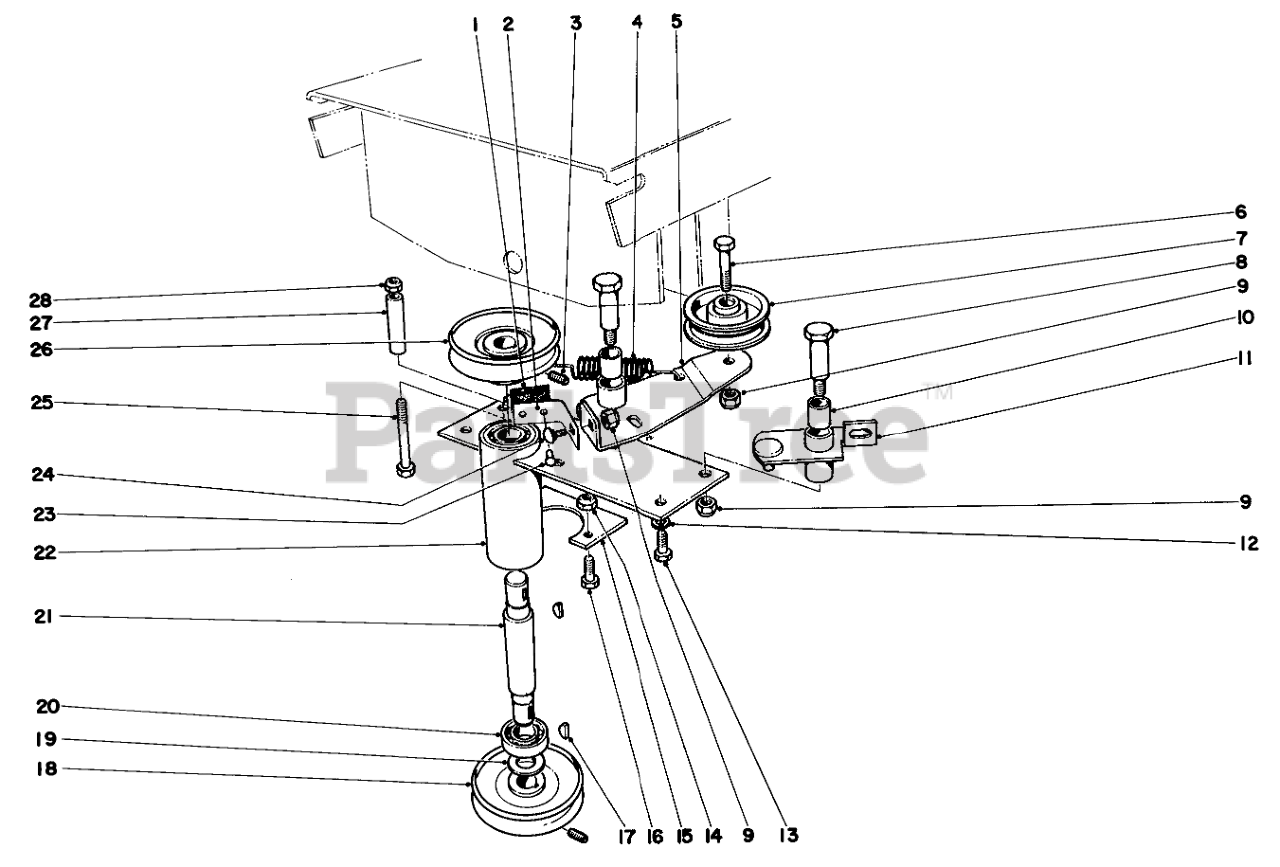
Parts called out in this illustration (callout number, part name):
1	BLADE BRAKE LINING
2	Brake Spring
3	SCREW-SET
4	Spring
5	Idler Plate
6	SCREW-HH
7	PULLEY-IDLER
8	Shoulder Bolt
9	NUT-LOCK, CONE
10	BUSHING
11	Pivot Bracket Incl. Ref. #10
12	WASHER-LOCK
13	SCREW-HH
14	NUT-LOCK, CONE
15	Retainer P.T.0. Tube
16	SCREW-HH
17	KEY-WOODRUFF
18	Pulley
19	Bearing Washer
20	Bearing
21	Shaft
22	P.T.0. Tube
23	Rivet
24	SCREW-CARR
25	SCREW-HH
26	Pulley
27	Spacer
28	NUT-LOCK, CONE
